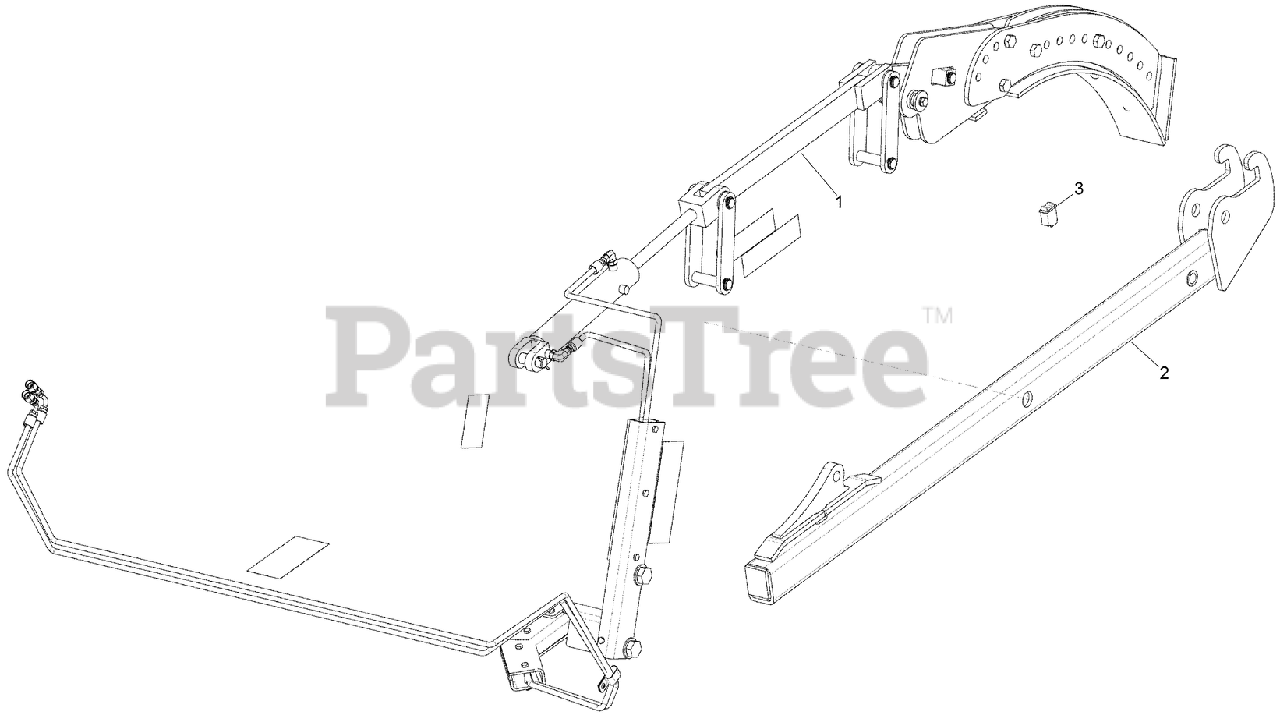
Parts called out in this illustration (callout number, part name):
1	KIT - Hydraulic Crumber
2	WELDMENT - Tube, Crumber
3	SWITCH-ROCKER, 2 POLE
5	BLADE - Hydraulic Crumber, 8 Wide Cut
